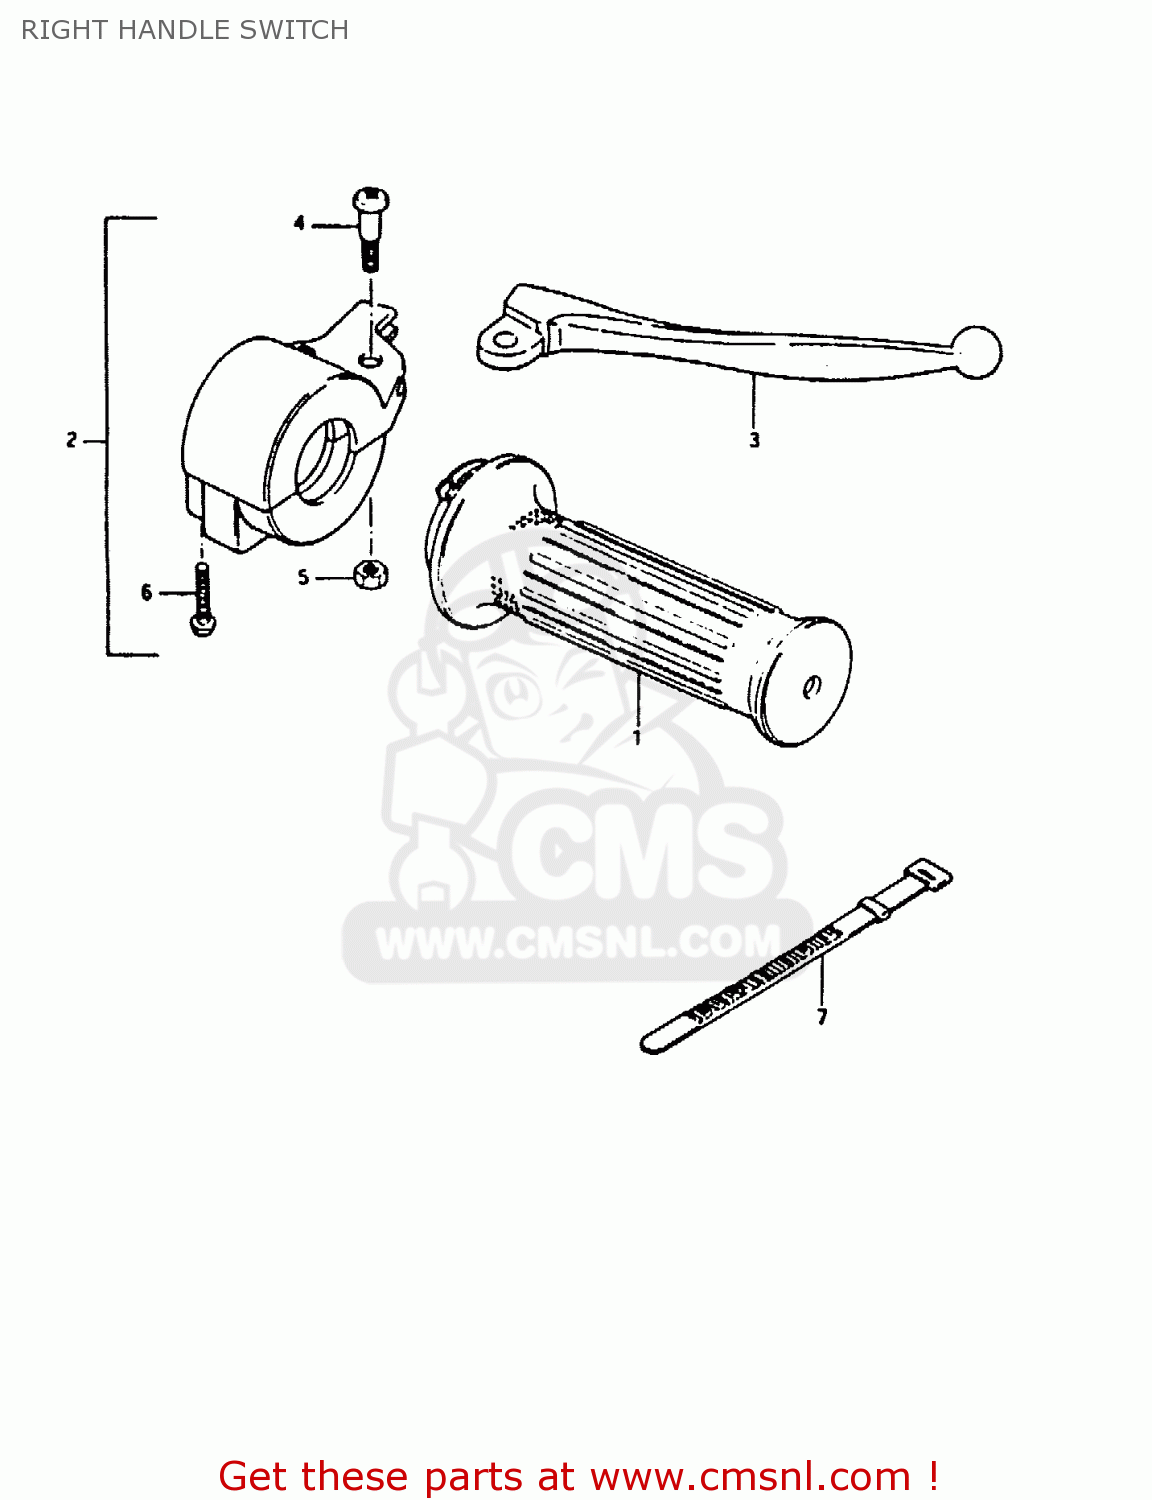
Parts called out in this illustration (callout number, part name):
1	GRIP,THROTTLE
2	BRAKE LEVER & SWITCH ASSY
3	LEVER
4	BOLT,LEVER
5	NUT,LEVER BOLT
6	SCREW
7	CLAMP(L:120)
